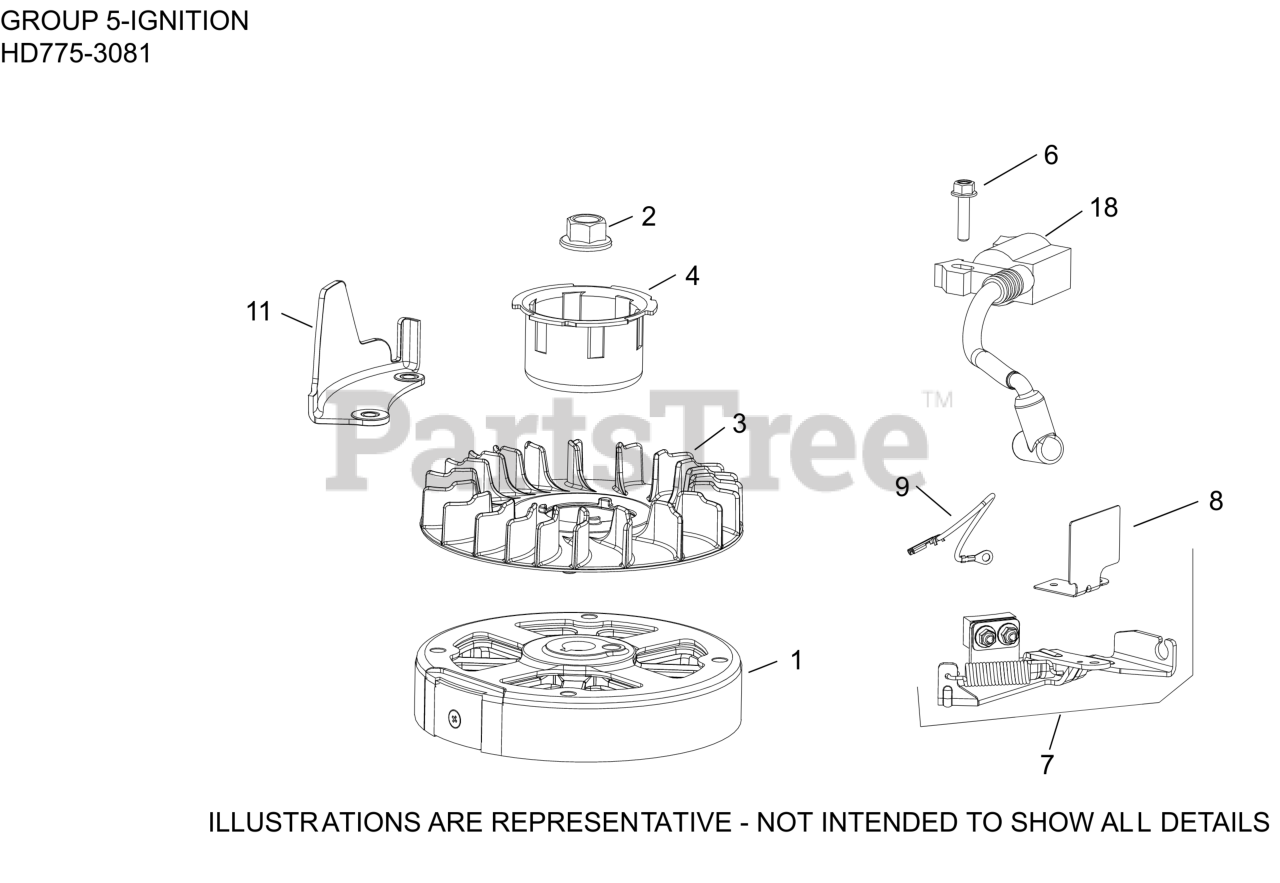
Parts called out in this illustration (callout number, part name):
1	FLYWHEEL ASSEMBLY
2	NUT, FLYWHEEL (W/SERRATIONS)
3	FAN, FLYWHEEL
4	CUP, DRIVE - (#1410905S)
6	SCREW, M6 X 25-(#25086436S)
7	BRAKE ASSEMBLY
8	GUARD, BRAKE - USE 14 314 30-S
9	LEAD, KILL (BRAKE TO IGN. MODULE)
11	GUARD, FINGER
18	MODULE IGNITION CAST IRON FLYWHEEL
